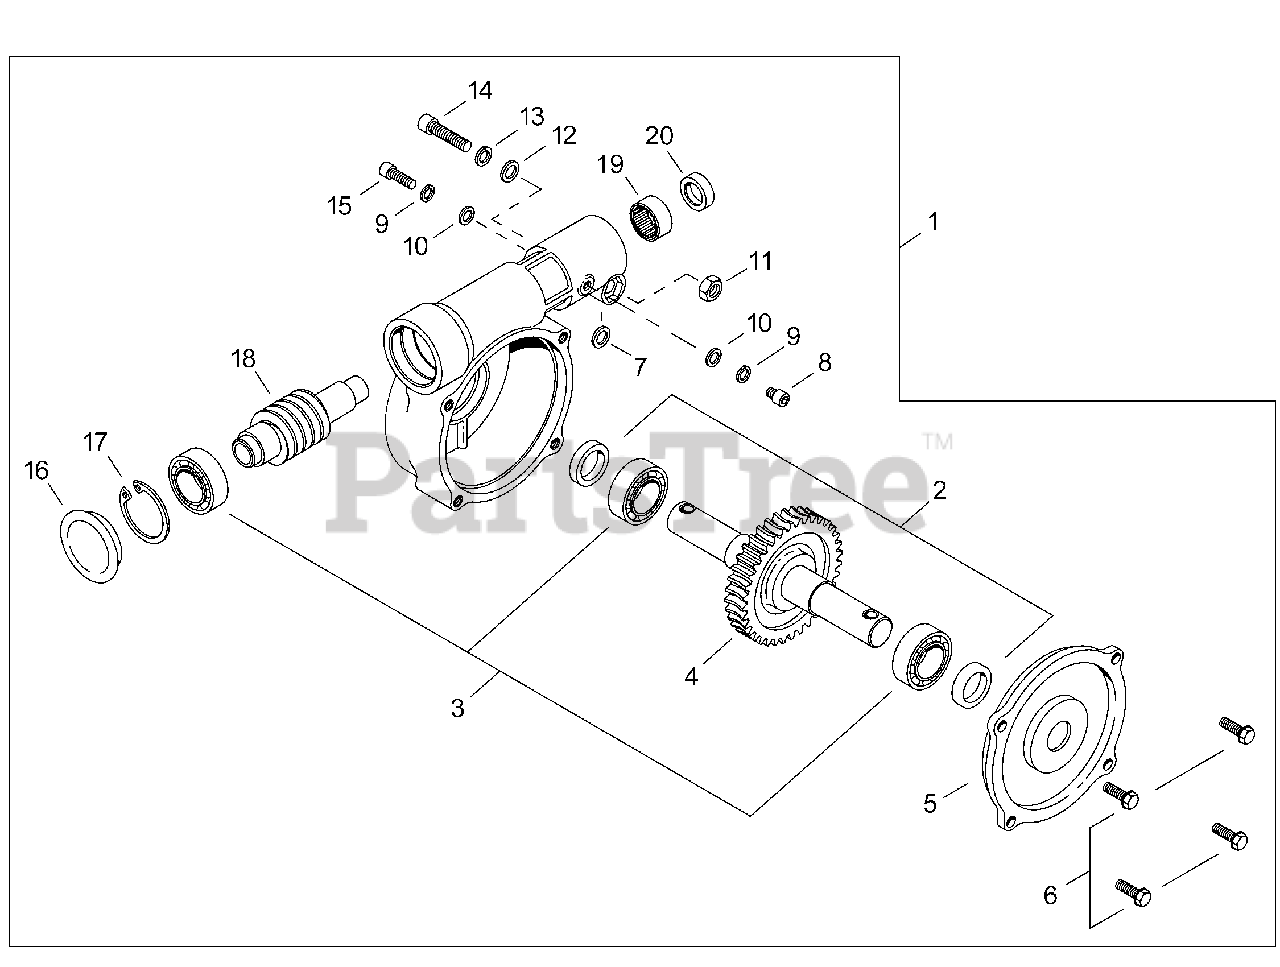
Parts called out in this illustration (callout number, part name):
1	GEAR CASE ASSY
2	SEAL, OUTPUT SEG TC15-24-5-20
3	BEARING, BALL PEER 6002
4	GEAR, DRIVE
5	COVER, GEAR CASE
6	SCREW SELF-TAPPING 5×16
7	WASHER M6
8	BOLT 5×8×0.80
9	WASHER, SPRING 5
10	WASHER, FLAT 5.5×10×0.8
11	NUT M6
12	WASHER M6
13	WASHER, LOCK M6
14	SCREW, SOCKET HEAD 6×30
15	BOLT 5×12
16	PLUG
17	RING, SNAP 34 MM
18	GEAR, WORM
19	BEARING, NEEDLE SCE 107 1/2 NF R
20	SEAL, INPUT SCG TC-12-21-6
